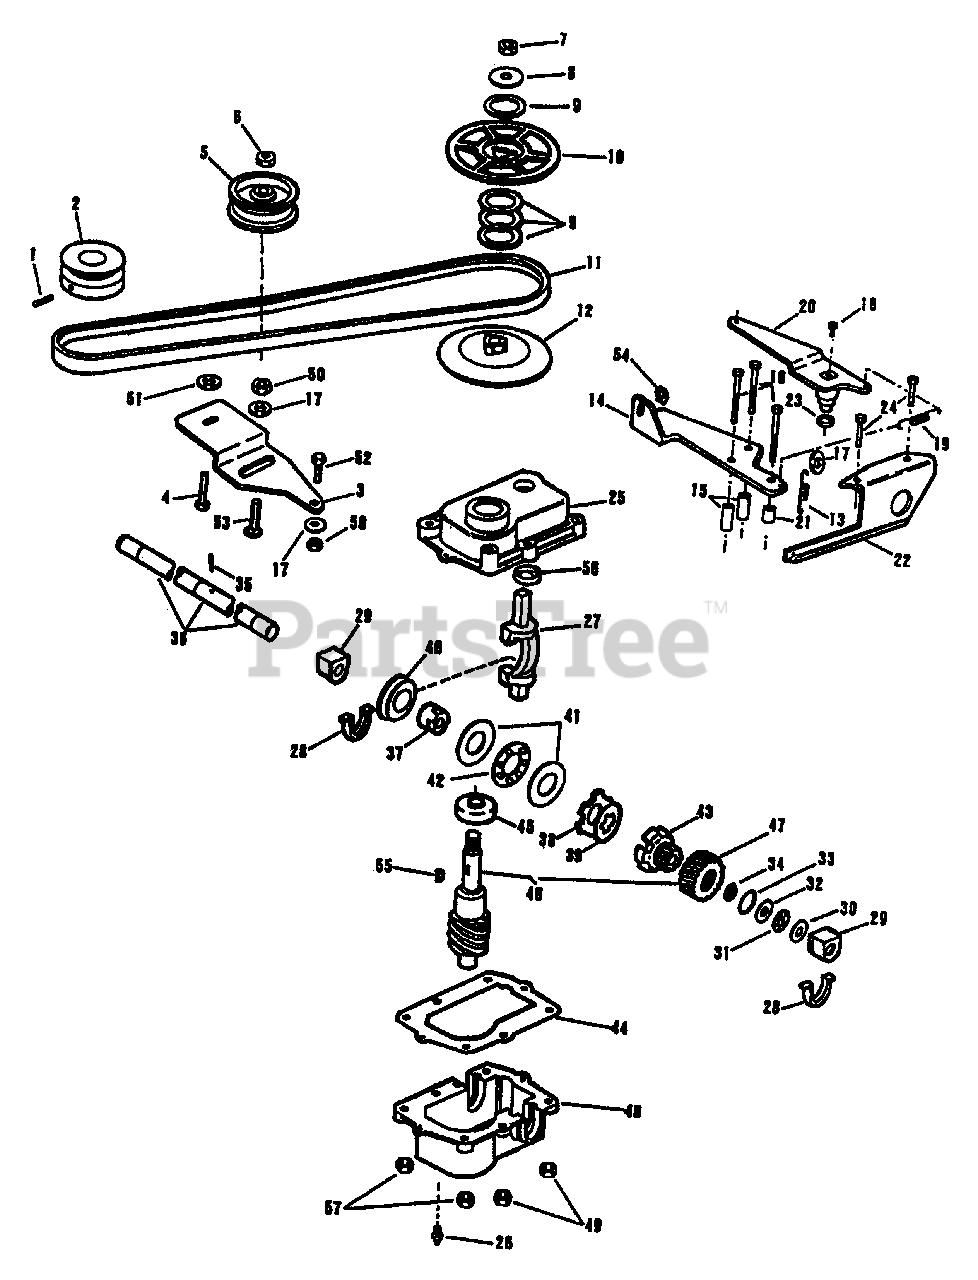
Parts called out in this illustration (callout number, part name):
1	Set Screw
2	Pulley-Engine
3	Bracket and Idler Assembly
4	Screw
5	Pulley-Idler
6	Nut
7	Nut
8	Washer
9	Washer
10	Pulley-Upper Half
11	V-Belt
12	Pulley-Lower Half
13	Extension Spring
14	Conduit Anchor Bracket
15	Spacer
16	Screw
17	Washer
18	Screw
19	Extension Spring
20	Shift Arm and Hub Assembly
21	Spacer
22	Tensioner Bracket
23	O-Ring
24	Hex Hd. Cap Screw
25	Gearcase-Upper
26	Plug
27	Shift Fork
28	Packing
29	Bearing & Seal-Gearcase
30	Thrust Washer
31	Thrust Bearing
32	Thrust Washer
33	Thrust Washer
34	Retaining Ring
35	Pin
36	Driveshaft
37	Driven Sleeve
38	Driver Plate
39	Driven Plate
40	Collar
41	Thrust Washer
42	Bearing
43	Driver
44	Gasket
45	Bearing
46	Worm Wheel and Shaft
47	Worm Wheel
48	Gearcase-Lower
49	Nut, Lock
50	Nut
51	Washer
52	Screw
53	Square Neck Bolt
54	Retaining Ring
55	Key
56	Seal Guide
57	Nut, Lock
